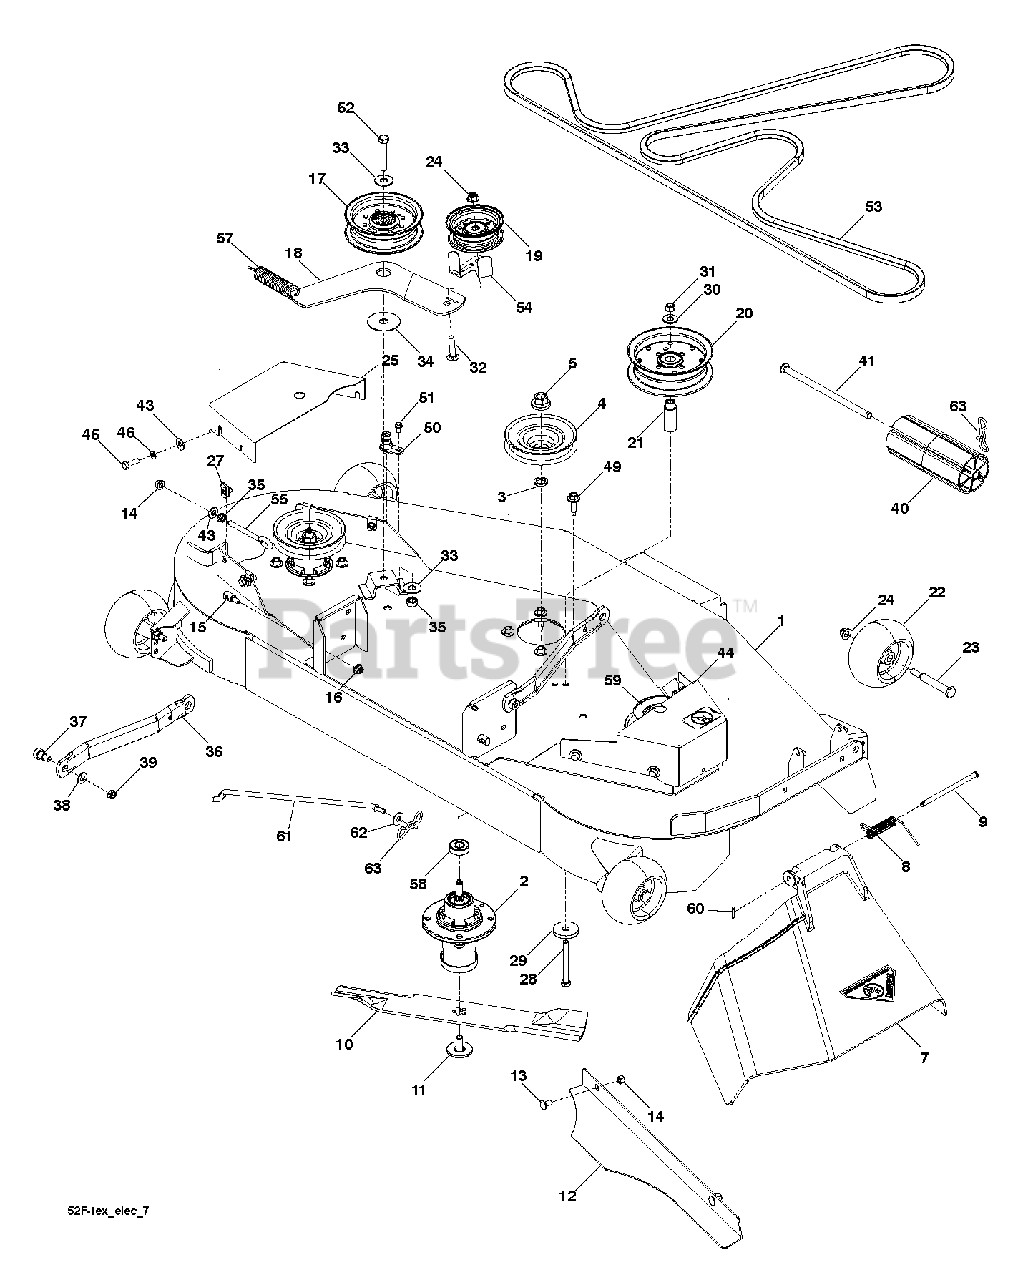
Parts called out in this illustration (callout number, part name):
2	HOUSING ASM
3	WASHER.SPACER USE 532187690
4	PULLEY.IDLER.DRIVEN
5	NUT.FLANGE.LOCK.TOP
7	DISCHARGE CHUTE 52"
8	SPRING - TORSION
9	PIN-CLEVIS 5/16 DIA X 5.19 ZD
10	BLADE, 17.75 X 2.5 X .25
11	BOLT.WASHER.ASM.7/16-2
12	PLATE, 52" CONF. BLK
13	BOLT
14	NUT.71038.31-18.HEX.NYLOCK
15	STUD.FASTNER.W/ANTI-ROTATE
16	5/16-18 NYLOC FLANGE NUT
17	PULLEY.IDLER.MWR.STATI
18	ARM, IDLER, 52" BLK
19	PULLEY, IDLER, FLAT
20	PULLEY, IDLER
21	BUSHING, IDLER
22	WHEEL GAGE DONUT
23	BOLT.SHOULDER.3/8-16X3-5/8
24	NUT 3/8-16 HEX FLG NYLOC ZD
27	U-CLIP 5/16-18 NUT RETAINER
28	HCS 3/8-16 X 3-1/2 GR5 ZD
29	SPINDLE WASHER
30	WASHER 3/8 FLAT
31	NUT 3/8-16 NYLOC
32	RHSNB 3/8-16X1-3/4
33	WASHER 7/16 FLAT ZD
35	NUT.LOCK.FLANGE.7/16
36	ARM.SUSPENSION.MOWER
37	SB 3/8-16 X 3/8 SKT HD ZD
39	NUT HEX 3/8-16 NYLON, THIN
40	NOSE ROLLER 48"
41	ROD.ROLLER.NOSE.NARROW.48"
43	WASHER
43	SRPING.TORSION.RETAINE
46	Lock Washer, 5/16
49	Hex Washer Head Bolt, .313-18 X 1.19
50	PORT.WASHOUT
51	SCREW
52	Hex Bolt, 7/16-14
53	BELT, 143.5" EL
54	GUARD, BELT
55	EYE BOLT 5/16 X 3.50
57	SPRING
59	PULLEY, COLLECTION 48
60	RETAINER CLIP
61	ROD.ANTI.SWAY.48/54"TE
62	WASHER
63	PIN.COTTER.5/16.BOW TI
